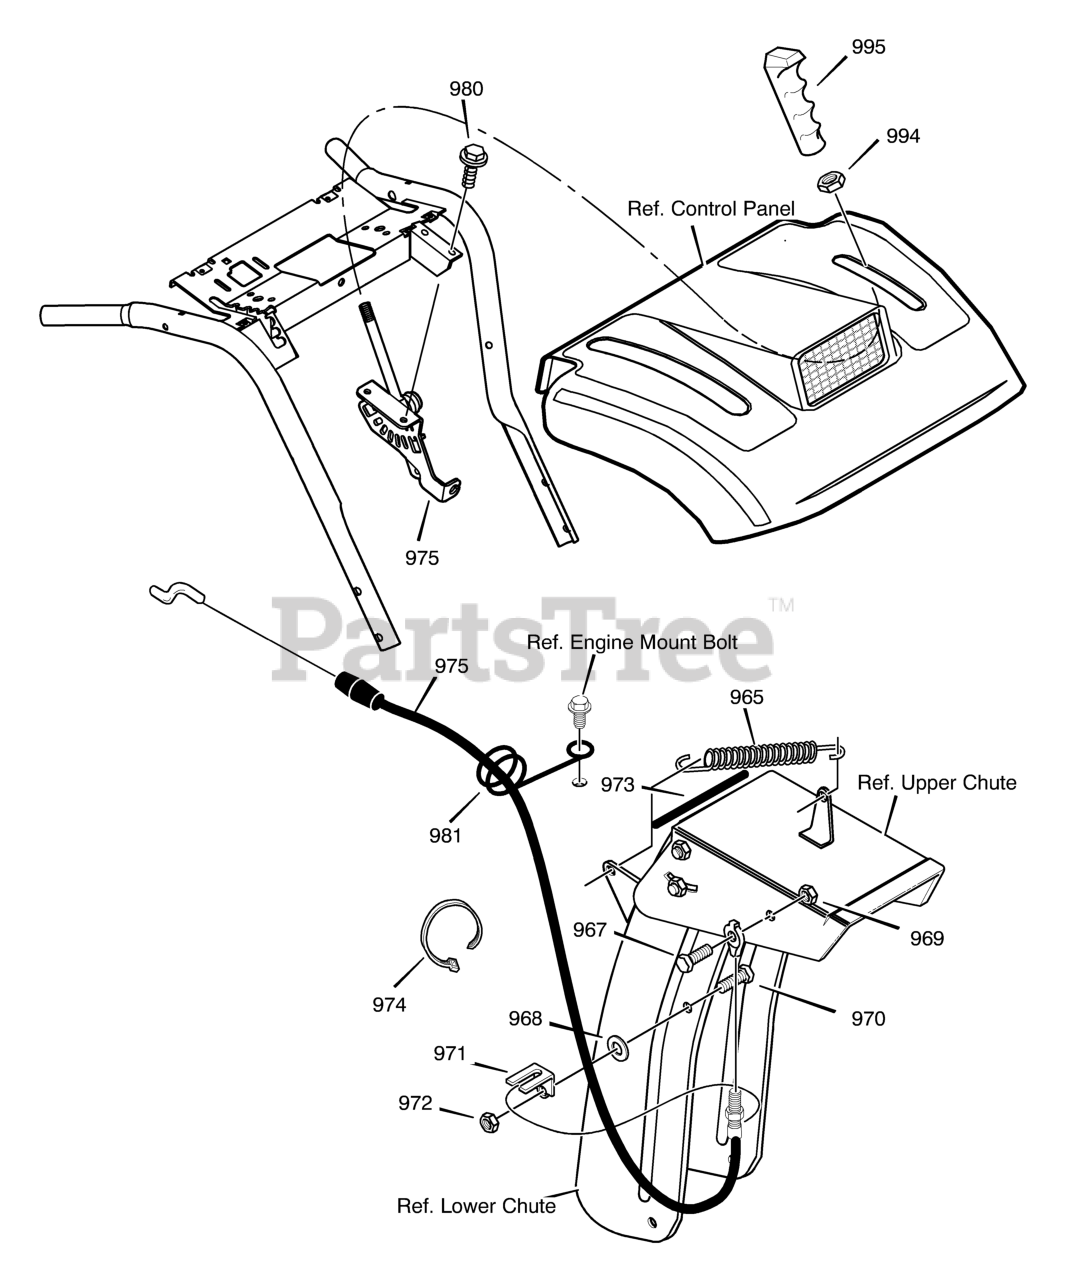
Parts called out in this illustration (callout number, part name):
965	TENSION SPRING
967	BOLT, SHOULDER
968	FLATWASHER
970	SCREW, 5/16-18 x 0.75
971	BRACKET, CABLE CHUTE
972	NUT, 5/16-18
973	TRIM STRIP, BLACK
974	TIE, CABLE
975	CABLE, CHUTE DEFLECTOR
980	SCREW
981	WIRE FORM, CHUTE CABLE
994	NUT, 3/8-16
995	KNOB, SHIFT
